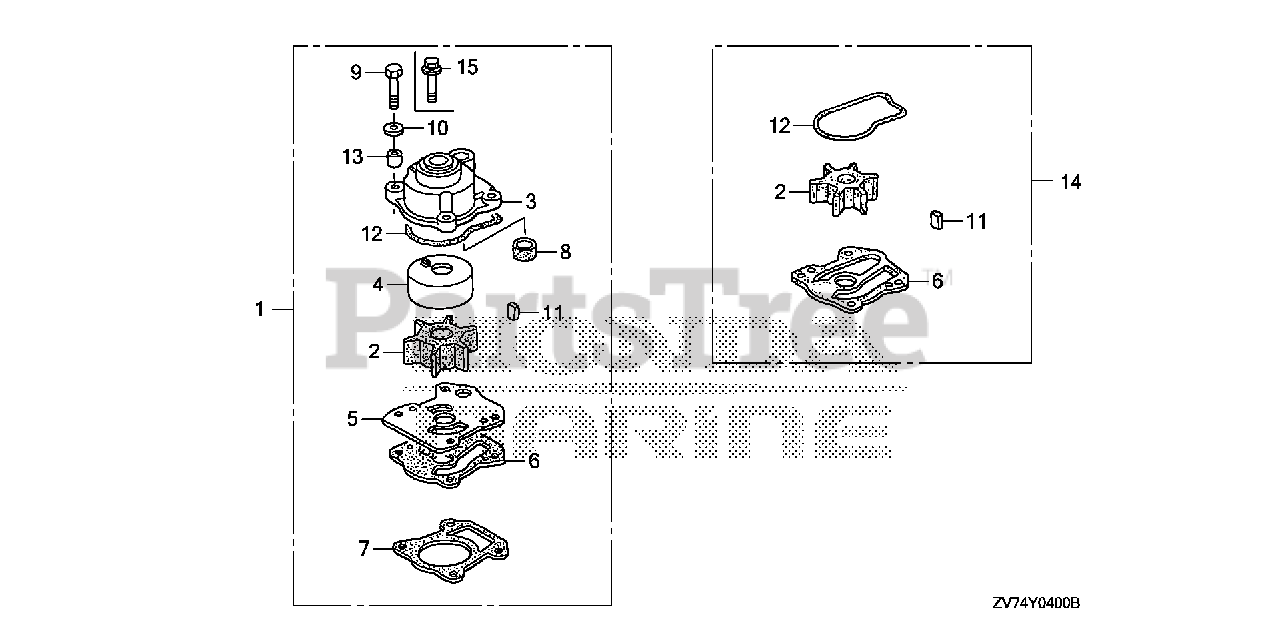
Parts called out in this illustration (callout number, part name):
1	PUMP KIT, IMPELLER
2	IMPELLER, PUMP
3	HOUSING, IMPELLER
4	LINER, PUMP
5	COVER, IMPELLER
6	GASKET B, IMPELLER
7	GASKET, WATER PUMP
8	RING, WATER TUBE SEAL
9	BOLT, HEX. (6X40)
10	WASHER (6MM)
11	KEY, WOODRUFF (5MM)
12	O-RING, WATER PUMP
13	COLLAR, IMPELLER HOUSING
14	PUMP KIT, IMPELLER
